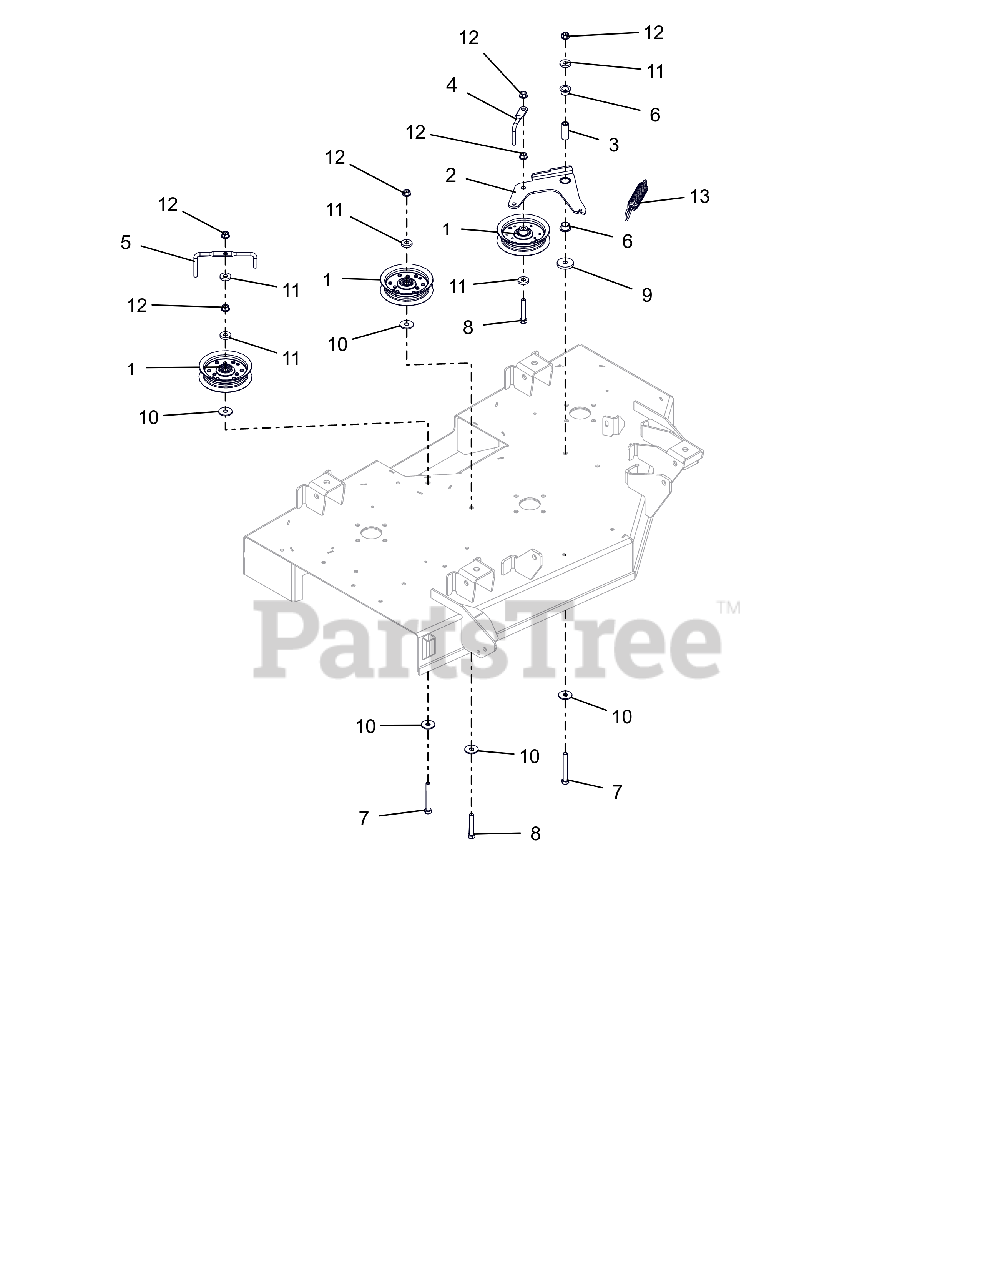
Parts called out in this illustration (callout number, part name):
1	ASM, IDLER 4"
2	WLDMT, IDLER ARM-42"
3	SPACER, .375IDX.625ODX1.66 PM
4	WIREFORM, BELT FINGER
5	WIREFORM, BELT FINGER
6	BSHG-FLG, .625X.750X.500X1.00
7	BLT, HEX .38-16X3.00F G5 ZCC
8	BLT,HEX .38-16X2.25 G5 ZCC
9	WSHR, FLT .406X1.50X.245 ZCC
10	WSHR FL STL .406X1.25X.10ZC120
11	WSHR, FLT .406X1.00X.188 ZCC
12	NUT-LK-TOP-FLG .38-16 ZC120
13	SG-TENS .135X.98X6.0 WLD 62
